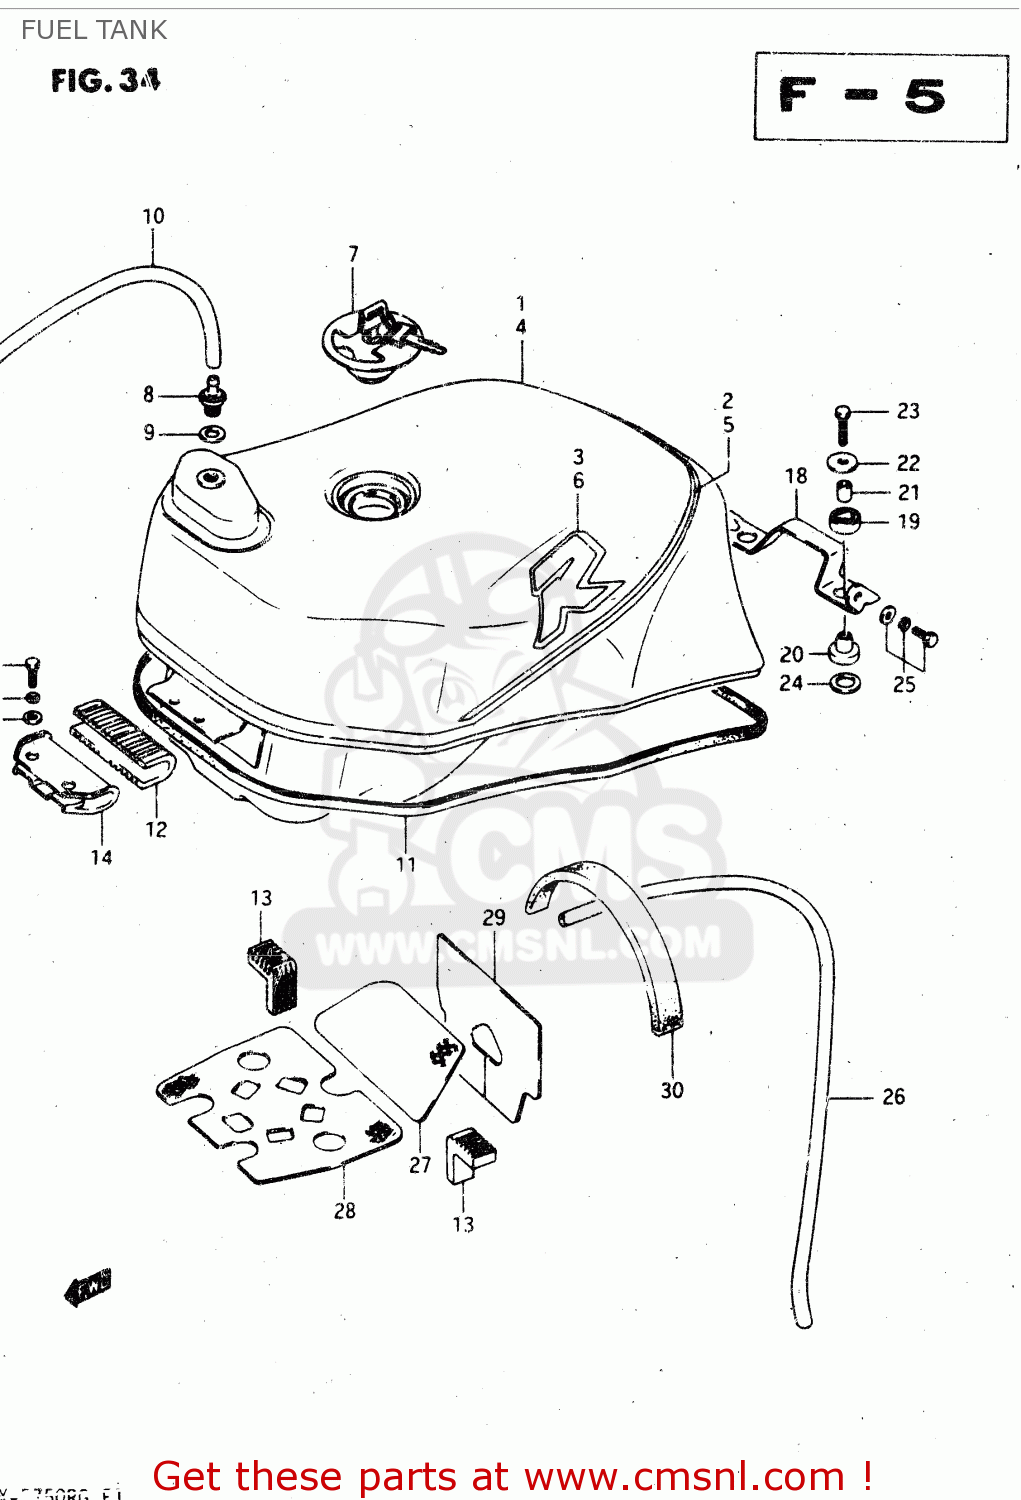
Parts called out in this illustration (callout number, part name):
1	TANK ASSY, FUEL
2	TAPE SET, FUEL TANK (RED)
3	EMBLEM
4	TANK ASSY, FUEL
5	TAPE SET,FUEL TANK
6	EMBLEM
7	CAP SET,FUEL TANK
8	PLUG, FUEL TANK BREATHER
9	GASKET(12.5X20X2.5) (NAS)
10	HOSE,FUEL
11	MOLDING,FUEL TANK
12	CUSHION,FUEL TANK,FRONT
13	CUSHION,FUEL TANK
14	BRACKET,FUEL TANK FR
15	BOLT
16	WASHER,LOCK
17	WASHER
18	BRACKET,SEAT SUPPORT,FRONT
19	CUSHION
20	CUSHION
21	SPACER
22	WASHER (6.5X24X1.6)
23	BOLT ,6X35
24	WASHER (12.5X24X1.6)
25	SCREW(6X16)
26	HOSE,FUEL
27	SHIELD,FUEL TANK HEAT
28	SHIELD,FUEL TANK HEAT
29	HEAT SHIELD,FUEL TANK
30	SHIELD,TANK & CLEANER
